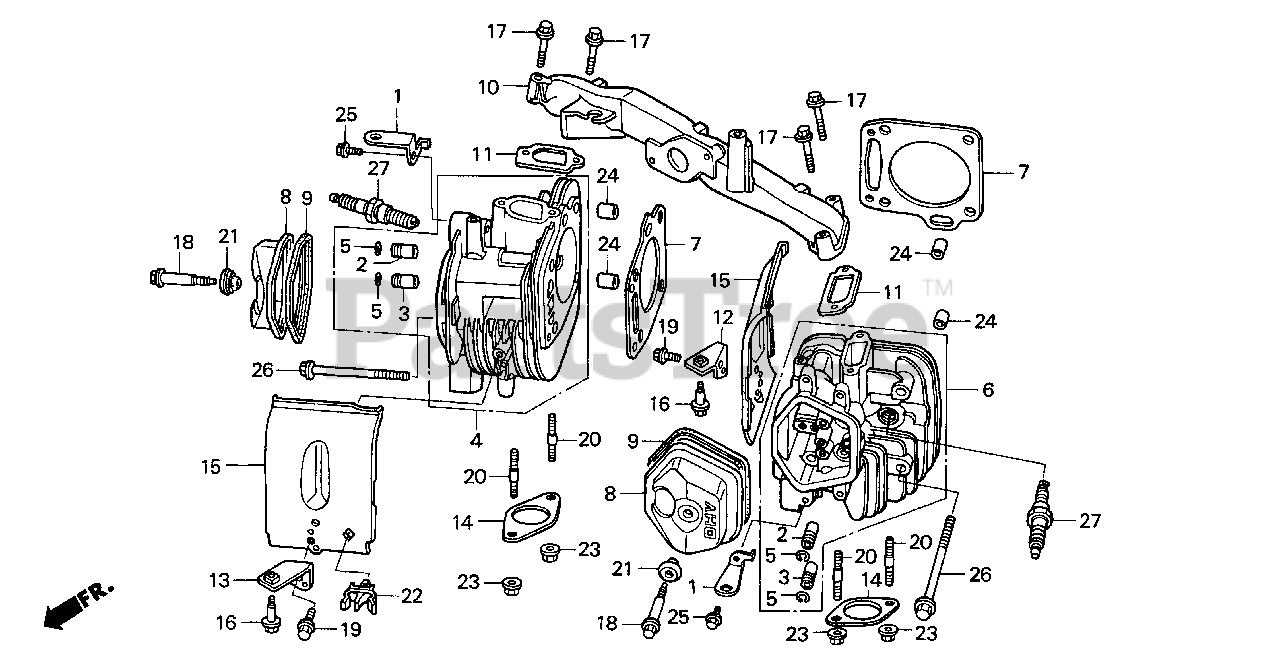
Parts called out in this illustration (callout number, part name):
1	HANGER, ENGINE
2	GUIDE, VALVE (OS)
3	GUIDE, EX. VALVE (OS)
4	CYLINDER HEAD (#1)
5	CLIP, VALVE GUIDE
6	CYLINDER HEAD (#2)
7	GASKET, CYLINDER HEAD
8	COVER, HEAD
9	GASKET, CYLINDER HEAD COVER
10	MANIFOLD, INLET
11	GASKET, IN. MANIFOLD
12	BRACKET, R. AIR CLEANER
13	BRACKET, L. AIR CLEANER
14	GASKET, EX. PIPE
14	GASKET, EX. PIPE (WACKER)
15	SHROUD, HEAD
16	BOLT, FLANGE (6MM)
17	BOLT, SOCKET (8X45)
18	BOLT, HEAD COVER
19	BOLT, FLANGE (6X14)
20	BOLT, STUD (8X22)
21	WASHER, HEAD COVER
22	CLIP, FUEL TUBE
23	NUT, FLANGE (8MM)
24	PIN A, DOWEL (12X20)
25	BOLT, FLANGE (8X20)
26	BOLT, FLANGE (10X80)
27	SPARK PLUG (J16CR-U)
27	SPARK PLUG (ZGR5A) (NGK)
